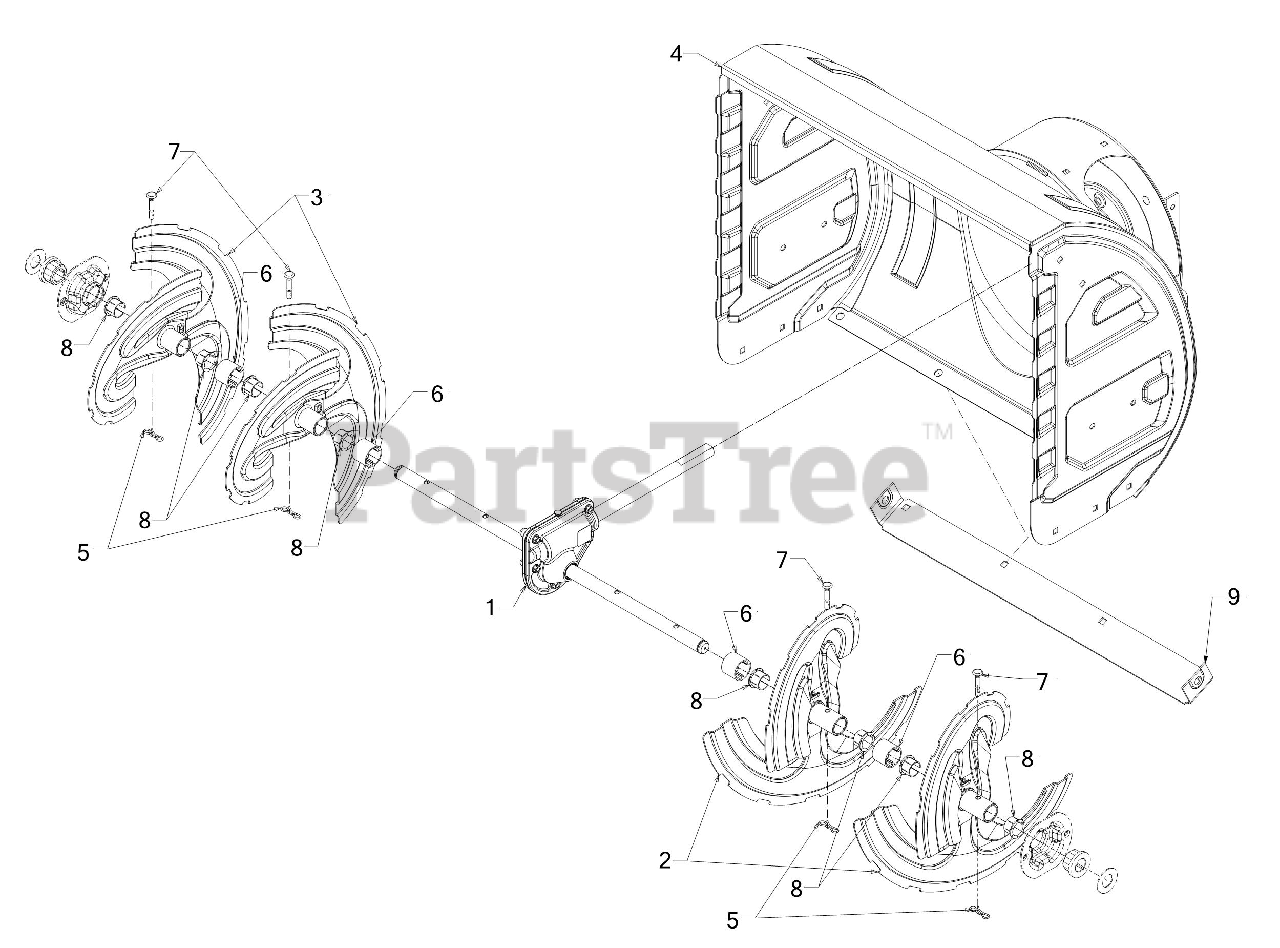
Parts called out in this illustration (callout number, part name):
1	24" GEARBOX ASSEMBLY
2	AUGER ASSEMBLY (LH)
2	SPIRAL - 30" x 12"
3	AUGER ASSEMBLY (RH)
3	SPIRAL - 30'' x 12''
3	SPIRAL - 30" x 12"
5	BOW TIE COTTER PIN 1/4-5/16
6	SPACER 1.25OD x .75ID X1.00 LG
7	SHEAR PIN .25 x 1.50 GR2
8	FLANGE BUSHING
9	24" SHAVE PLATE
